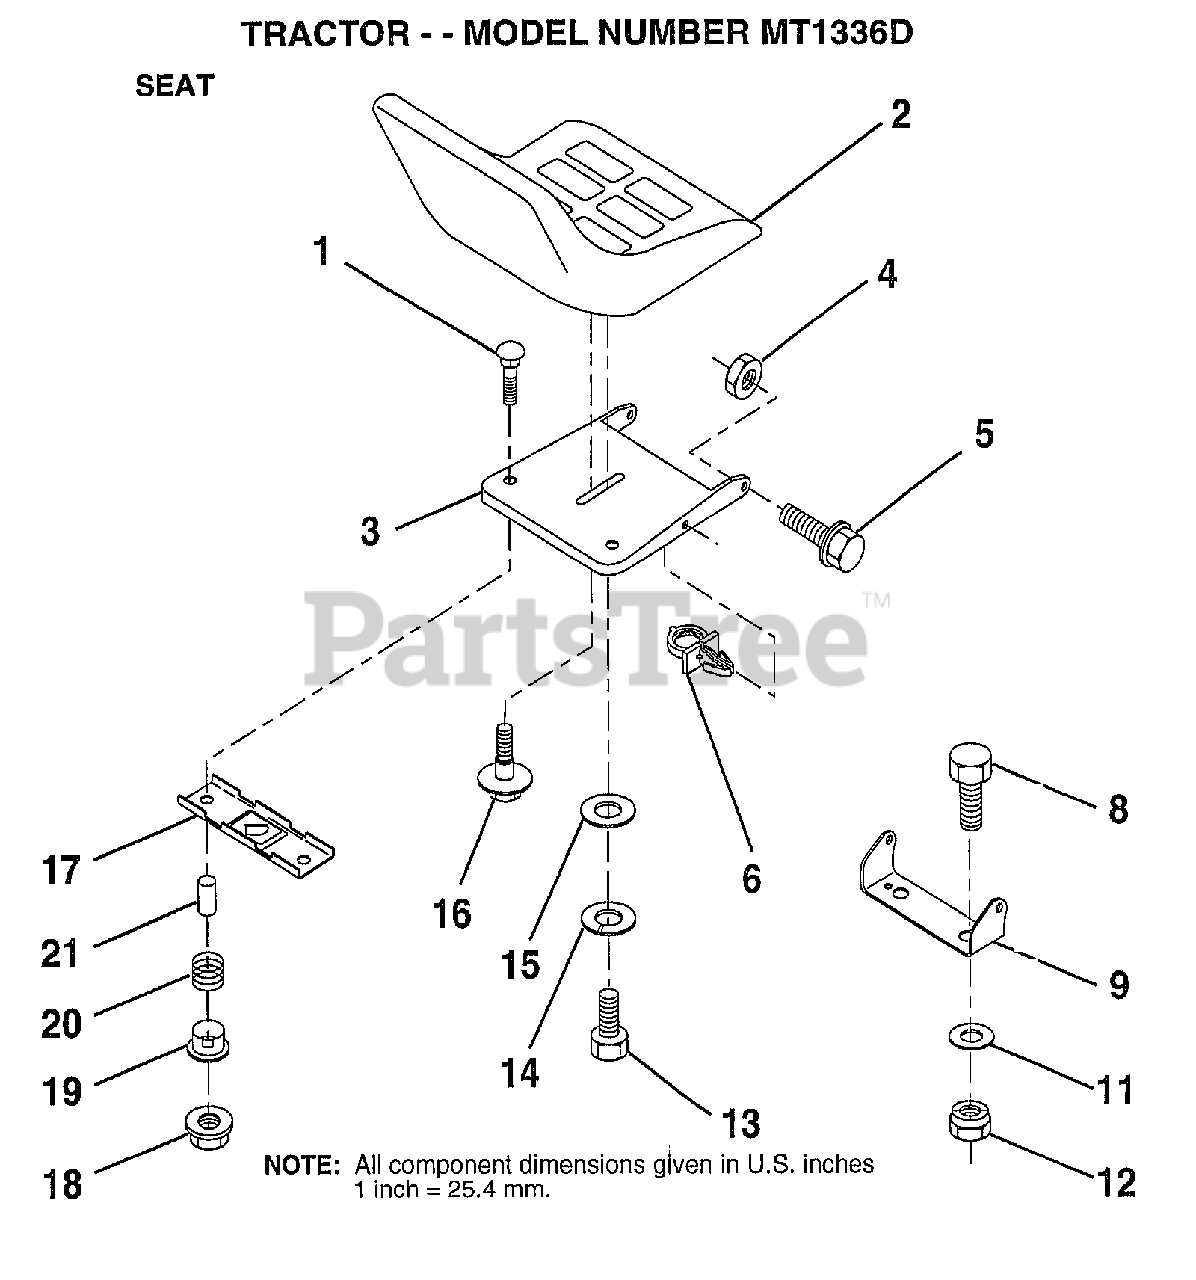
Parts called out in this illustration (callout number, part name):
1	BOLT-RD HD SQ NK
2	SEAT
3	PAN-SEAT
4	NUT
5	"BOLT,SHOULDER"
6	CLIP.PUSH-IN.HING
8	BOLT
9	BRACKET PVT SEAT
11	WASHER
12	NUT
13	BOLT
14	LOCKWASHER
15	WASHER
16	"BOLT,SHOULDER"
17	BRKT SWITCH
19	BUSHING
20	SPRING
21	SPLIT SPACER
